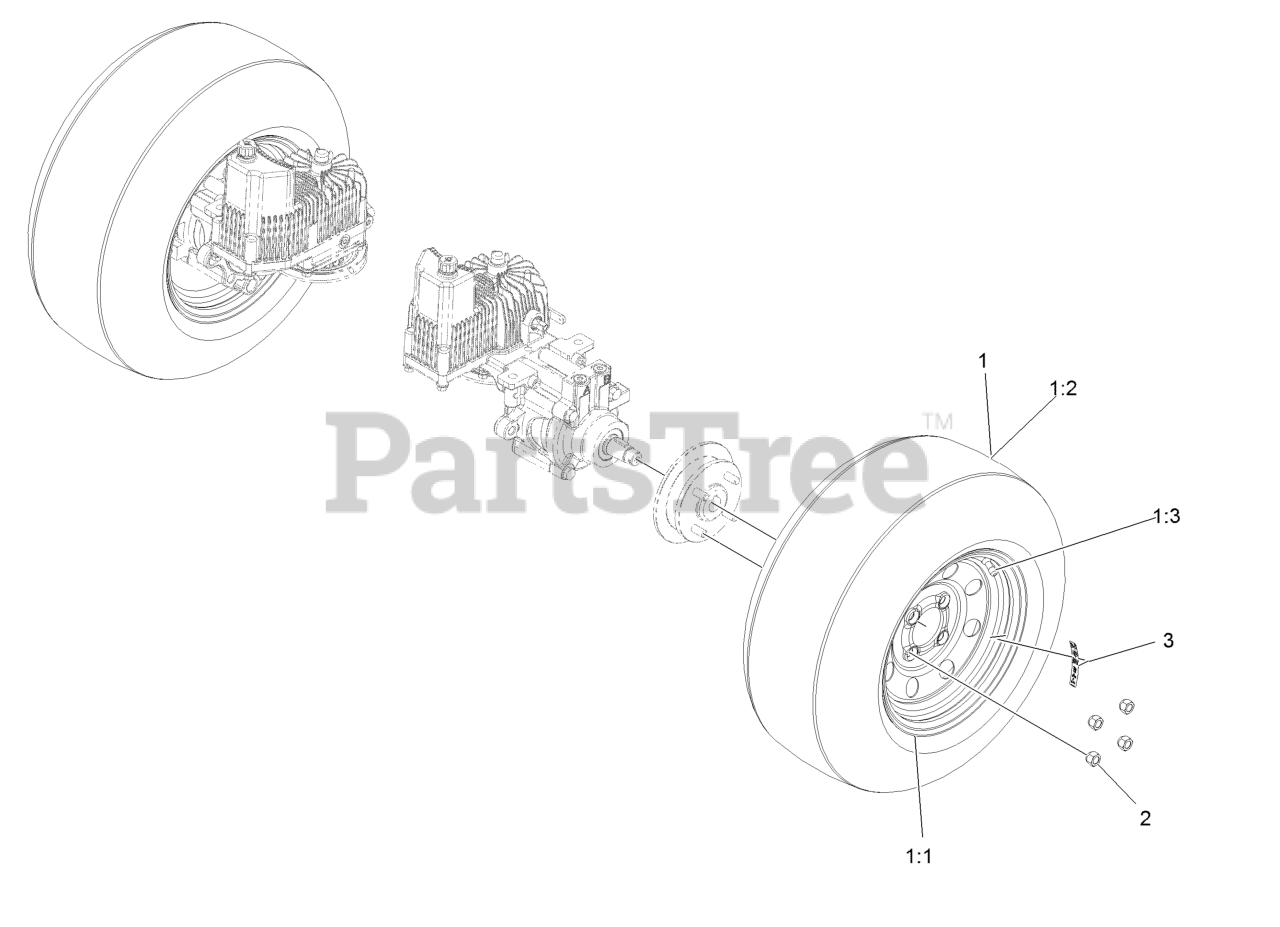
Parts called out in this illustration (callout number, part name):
1	Wheel And Tire ASM
1:1	ASM, Rim
1:2	Tire-Drive, 23X9.5-12
1:3	Stem-Valve
2	Nut-Lug 1/2-20
3	Decal-Torque, Wheel Hub Lug
